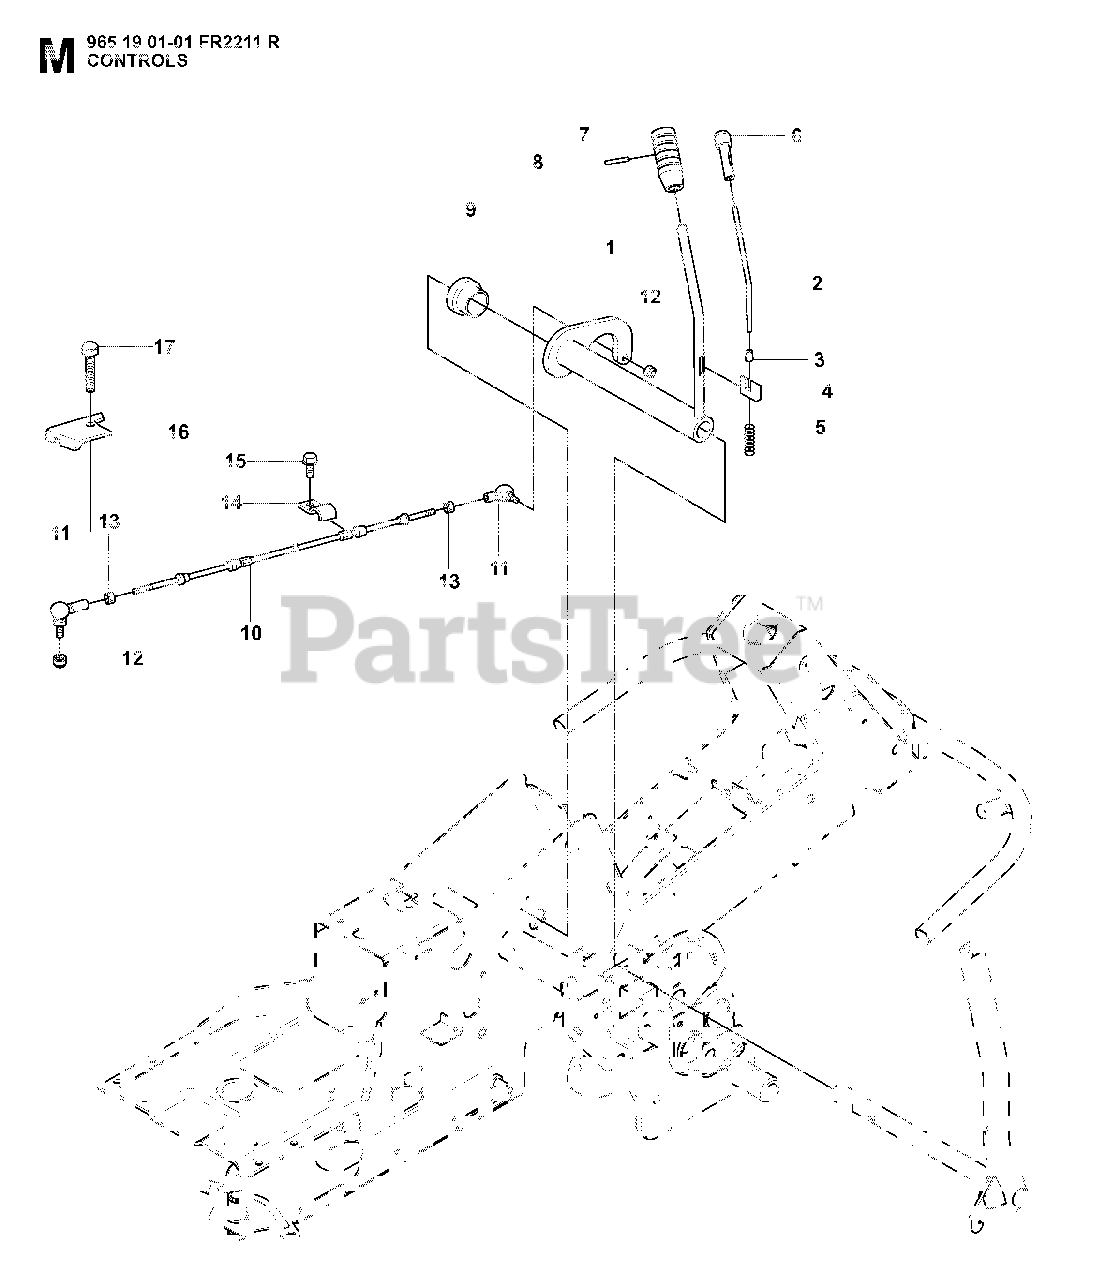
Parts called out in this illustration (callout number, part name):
3	END PIECE
8	SPRING PIN 3X24
9	BUSH
10	%ROD
11	CONNECTOR
12	LOCKNUT M5
